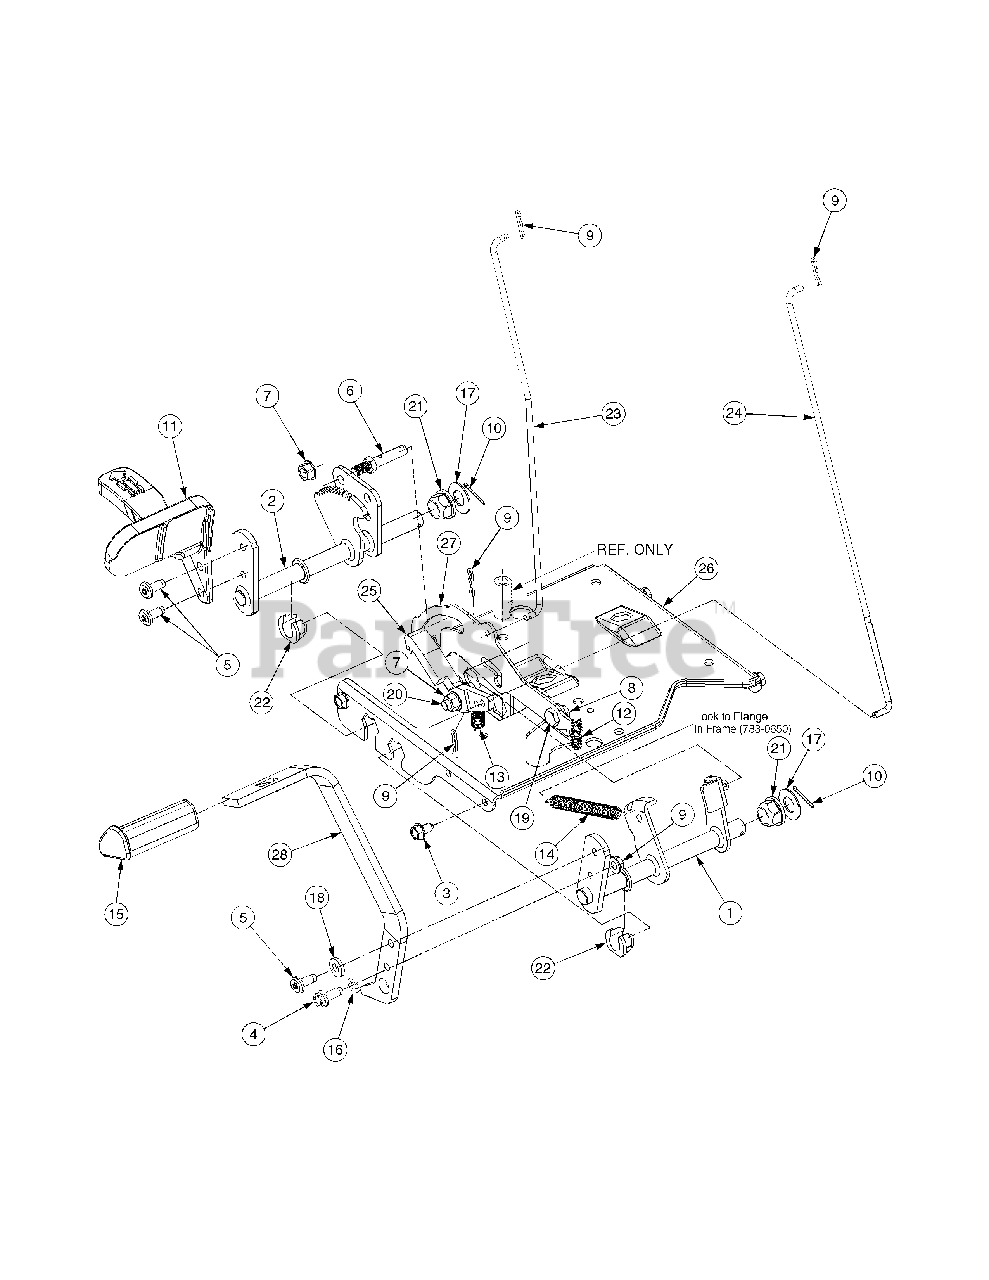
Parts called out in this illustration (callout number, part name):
4	Screw, Self-tapping, 5/16-18, 0.875
5	Screw, Torx Hd. Tapp. 5/16-18 x .75
6	Pin, 3/8-16, x 2.68 Lg
7	Nut, Flange Insert Lock, 3/8-16
8	Nut, Flange Lock, 5/16-18, Gr5
9	Pin, Cotter, .072 Dia. x 1.13 Lg
10	Pin, Cotter, 3/32, 1.0
11	Pedal, Control
12	Spring, Compression, .405 x 1.17
13	Spring, Extension, .50 OD x 1.41 Lg
14	Spring, Extension, .50 Dia x 6.37 Lg
15	Pad, Brake, Control
16	Washer, Lock, 5/16
17	Washer, Flat .64 ID x 1.24 x .06
18	Washer, Flat, .344 x .750 x .120
19	Shoulder, Screw .437 x 1.62 Lg
20	Screw, Shoulder, .50 x .27:3/8-16
21	Bearing, Hex Flange
22	Bearing, Hex Flange, .628 ID, Split
23	Rod, Control, Brake Lock
24	Rod, Control, Cruise
25	Latch, Cruise
27	Bracket, Lockout, Hydro
